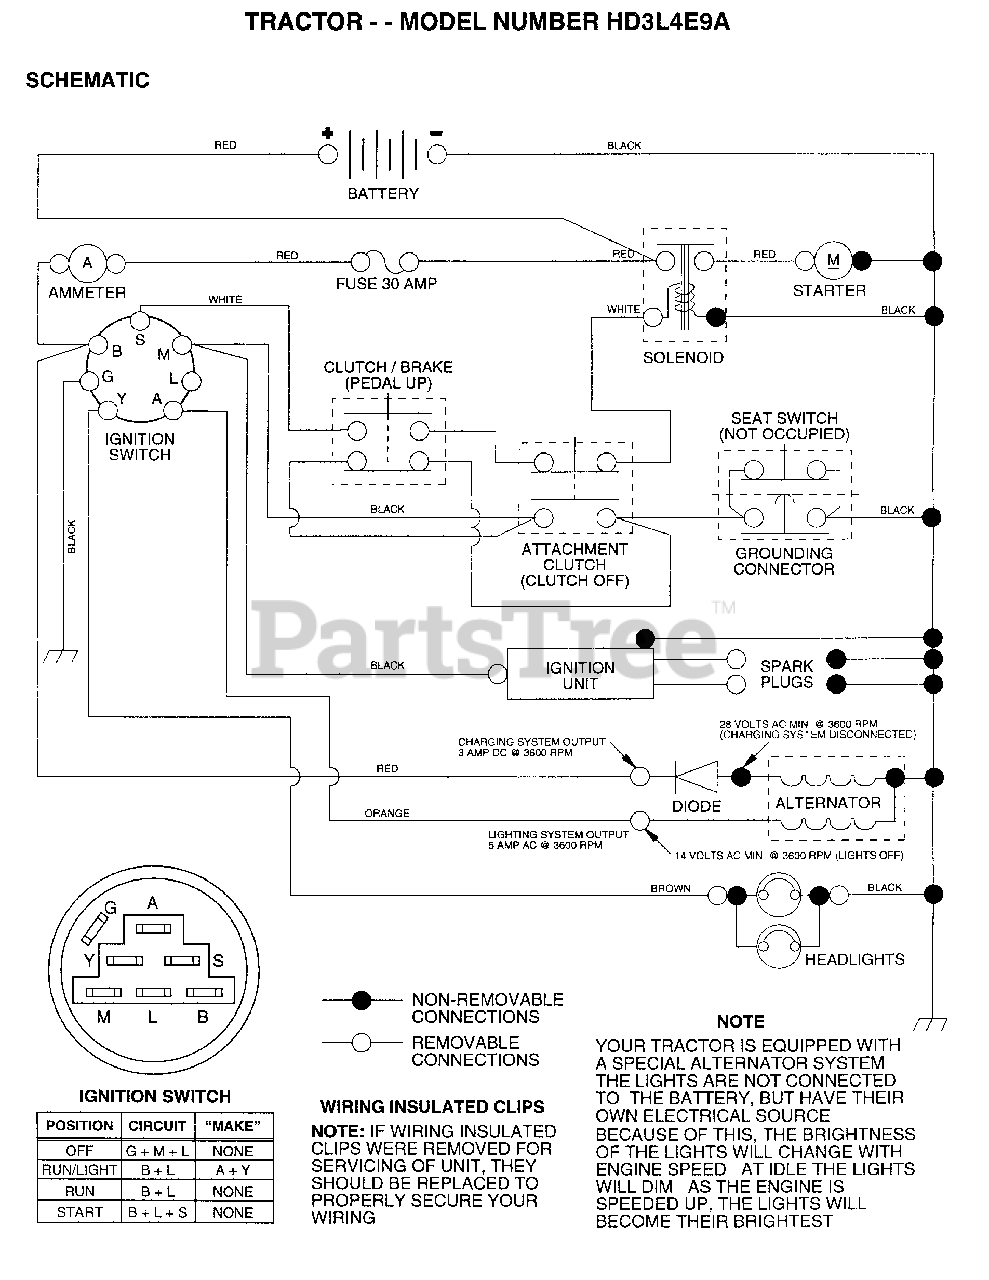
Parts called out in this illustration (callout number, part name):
2	BOLT LT
3	WASHER
4	LOCKWASHER
7	TUBE T
9	HOSE CLAMP T
15	FASTNER.SNAP-IN
20	NUT
21	"HARNESS,LIGHT SOC"
22	HEADLAMP BULB
24	CABLE-BATTERY T
25	CABLE.BTRY.6GA.RD
26	FUSE HYT
28	CABLE T
29	SWITCH SEAT
30	SWITCH IGN 4POS
31	NUT IGNITION
32	COVER KEY SWITCH
33	KEY
35	BRACKET LT
36	SCREW
38	BRACKET SWITCH IN
39	SWITCH INTERLOCKT
40	HARNESS.IGNITION
41	BOLT HXHD FIN
44	NUT HXKEP 1/4X20
52	PROTECTION LOOP
70	HARNESS.ENG.LT.
